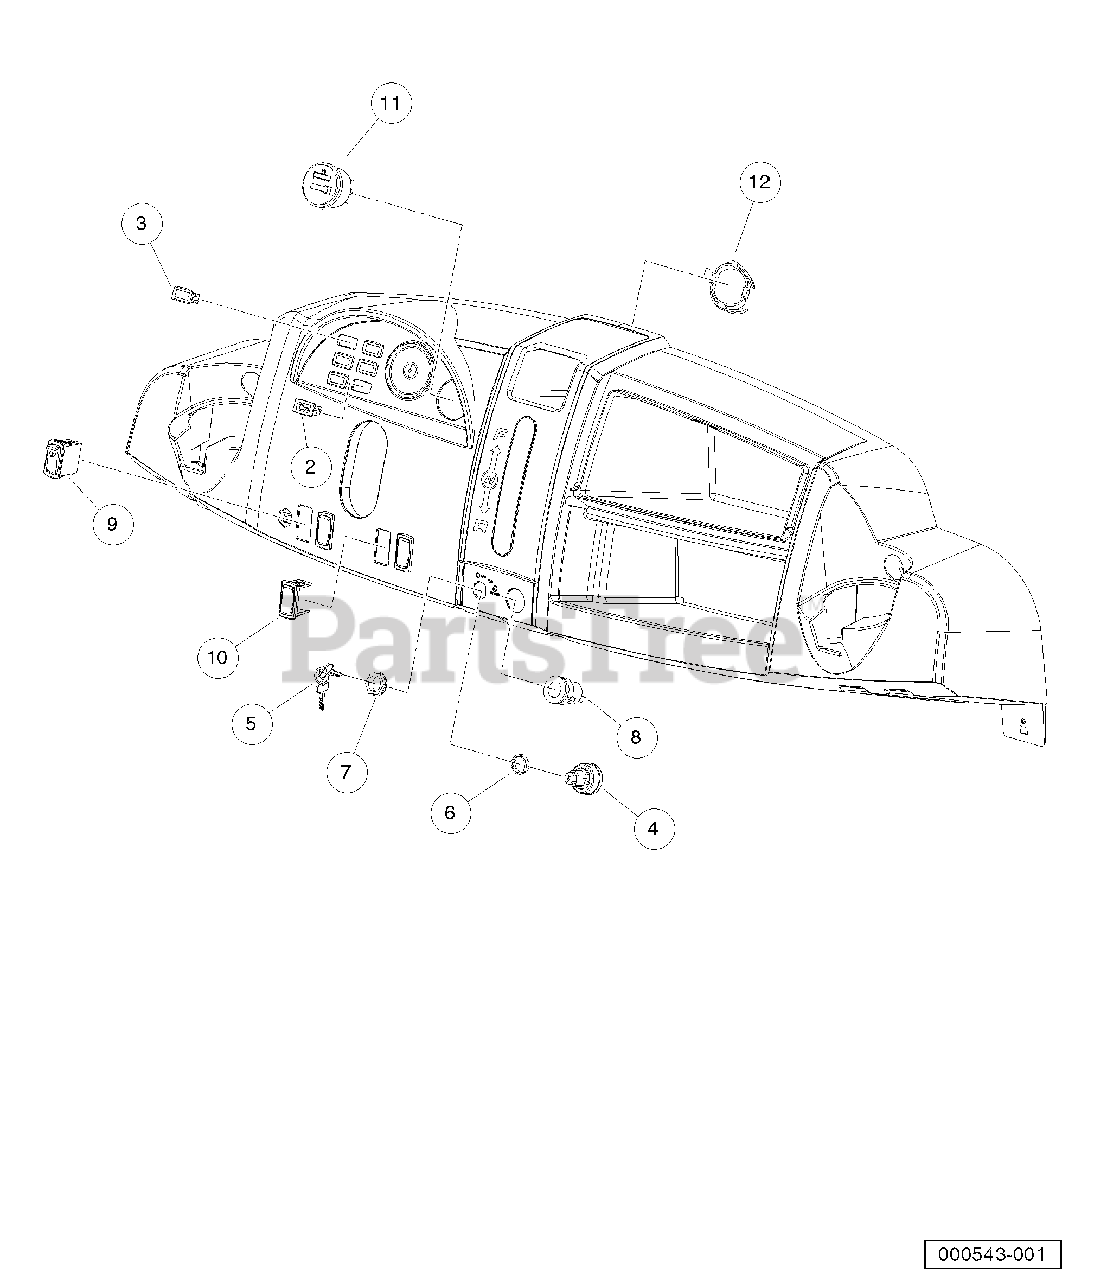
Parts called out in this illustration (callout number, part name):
1	Instl, Elec System, Gas
2	Light, Oil
3	Plug, Hole
4	Key Switch 12v Key Start
6	Spacer, Keyswitch
7	Nut, Key Switch
8	Receptacle, Accessory
9	Switch, Rocker, Light
10	Cover, Hole, Switch, Rocker
11	Gauge Fuel-hour Sep Gnd
12	Clip, Meter, Round
